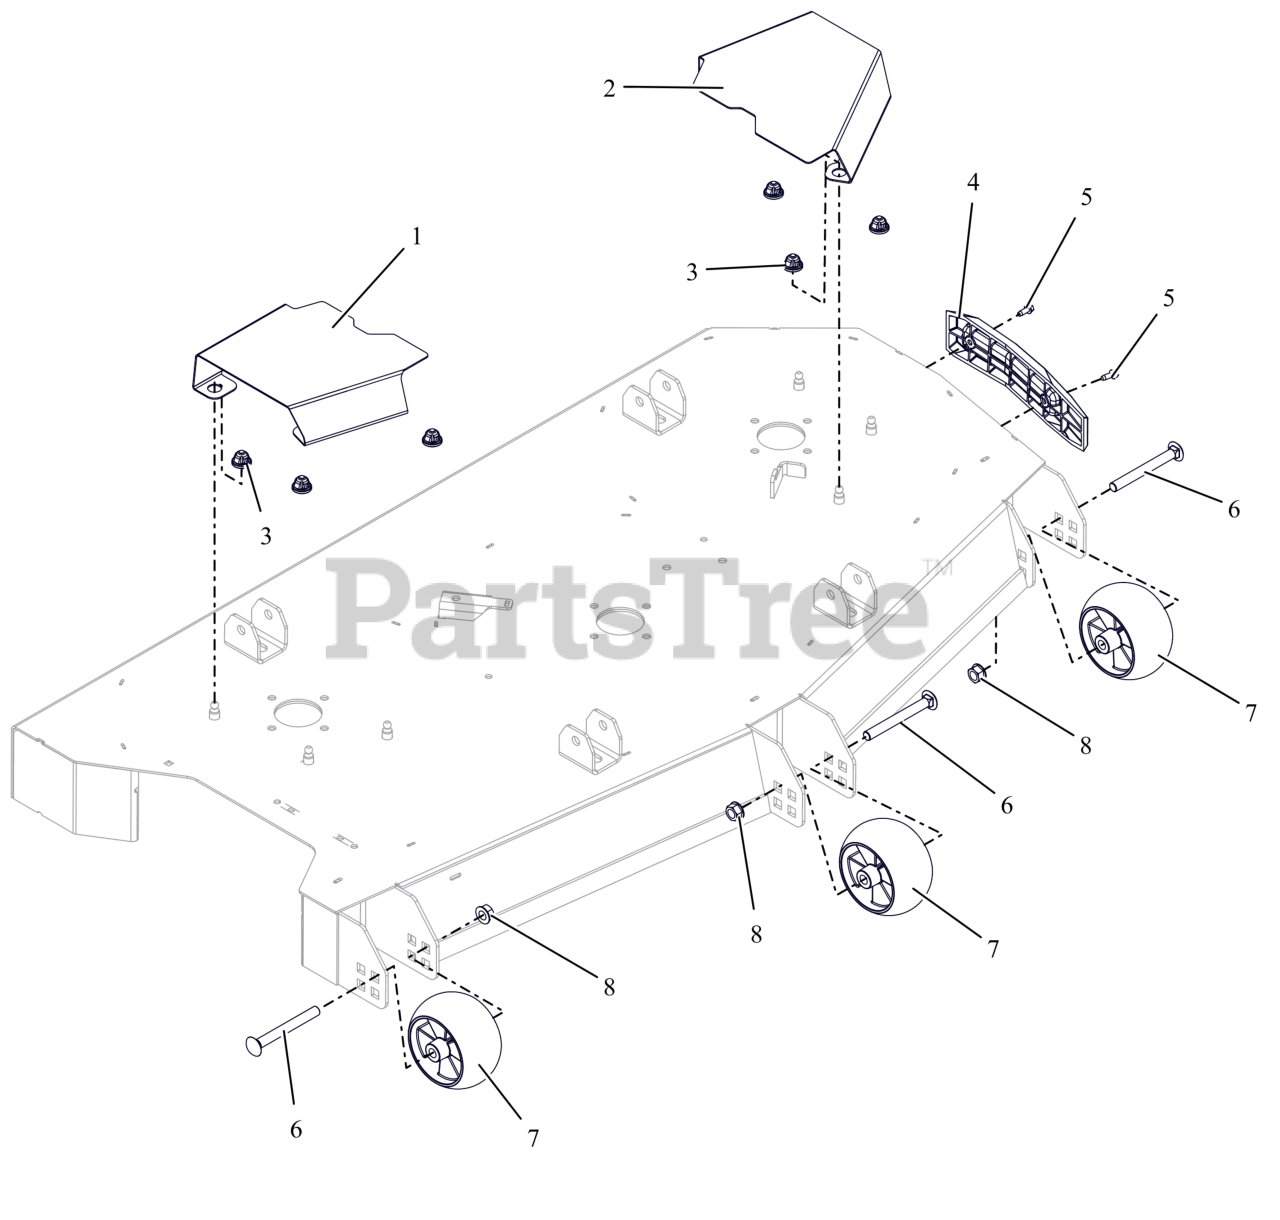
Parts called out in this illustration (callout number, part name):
1	COVER- RIGHT BELT
2	COVER- LEFT BELT
3	GROMMET, 10MM BOLLHOFF
4	BUMPER- DECK
5	SCR,TAP .25-20X.625 HWH ZCC
6	BLT,RHNS .50-13X4.50 G5 ZCC NS
7	WHEEL, ANTI SCALP - 5X3 CTR W/RIBS
8	NUT-LK-CTR-FLG .500-13 GG ZCC
